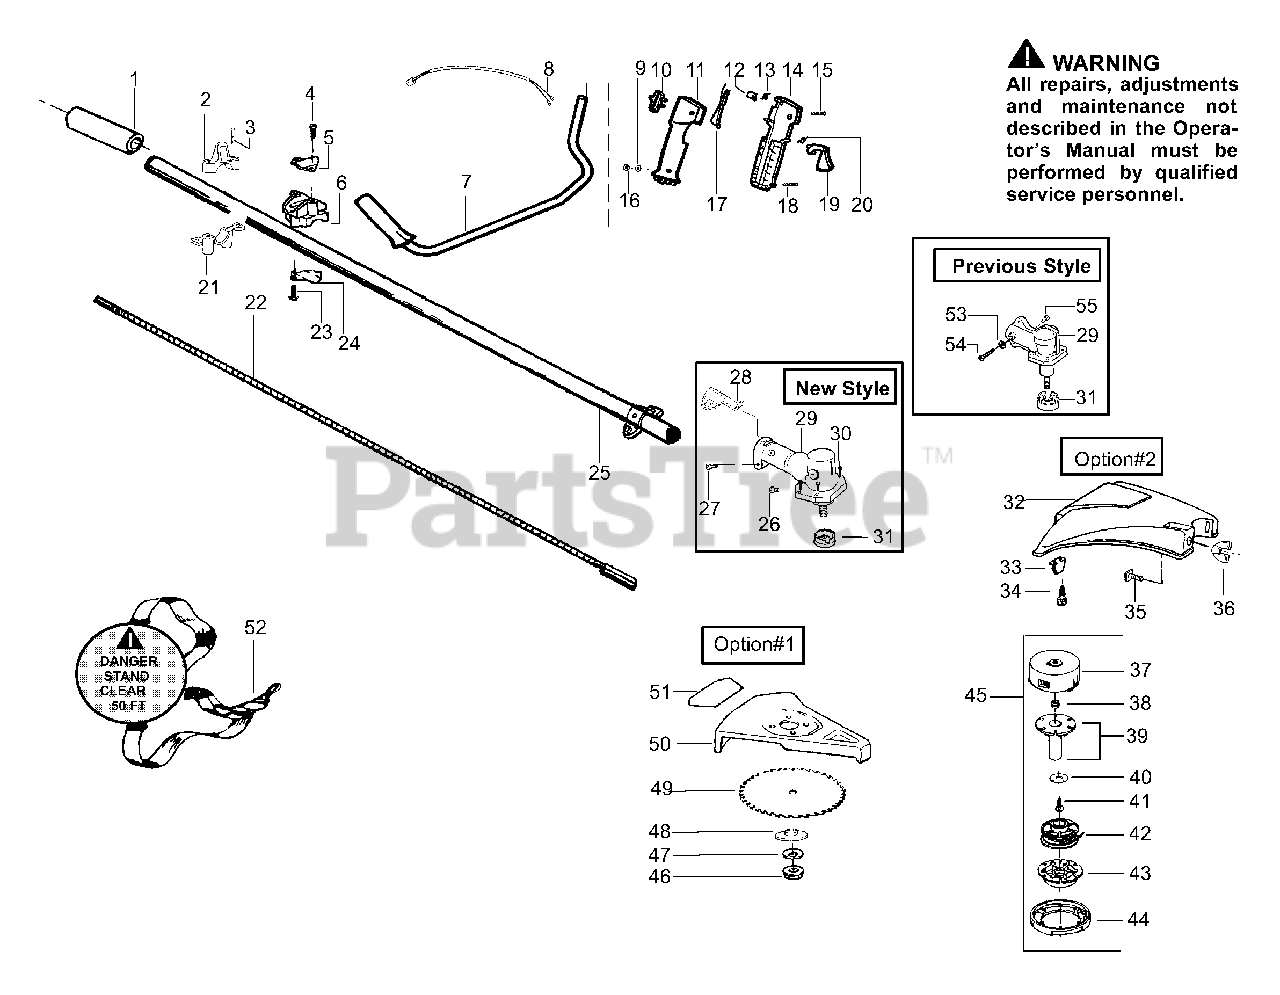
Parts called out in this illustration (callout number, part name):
1	Pad-Drive Shaft
2	Clamp-(upper)
5	Bracket-Handlebar
6	Clamp-Handlebar
7	Assy-Handlebar
8	Assy-Wire Harness
9	Washer, Split Lock
10	Switch-Rocker
11	Throttle Hsg. Right
12	Throttle Lock
13	Spring-Throttle Lock
14	Throttle Hsg. Left
17	Throttle Lockout
19	Trigger-Throttle
20	Spring-Trigger
21	Clamp-(lower)
24	Bracket-Handlebar
25	Assy-Drive Shaft
28	Bracket-Shield
29	Kit-Gear Box Ass'y.
31	Dust Cup
32	Kit-Shield Ass'y.
33	Line Limiter
34	Screw
36	Wingnut
37	Assy-Hub
39	Kit-Locking Plate
41	Screw
42	Spool w/Line
43	Release Button
45	Accy-Cutting Head
46	Nut-Flange
47	Washer-Spring Beve
48	Washer-Blade Ret.
49	Brush Blade
50	Kit-Blade Shield
51	Decal Blade Direction
52	Shoulder Strap
53	Washer (Type 1,2,3)
54	Screw (Type 1,2,3)
55	Screw (Type 1,2,3)
